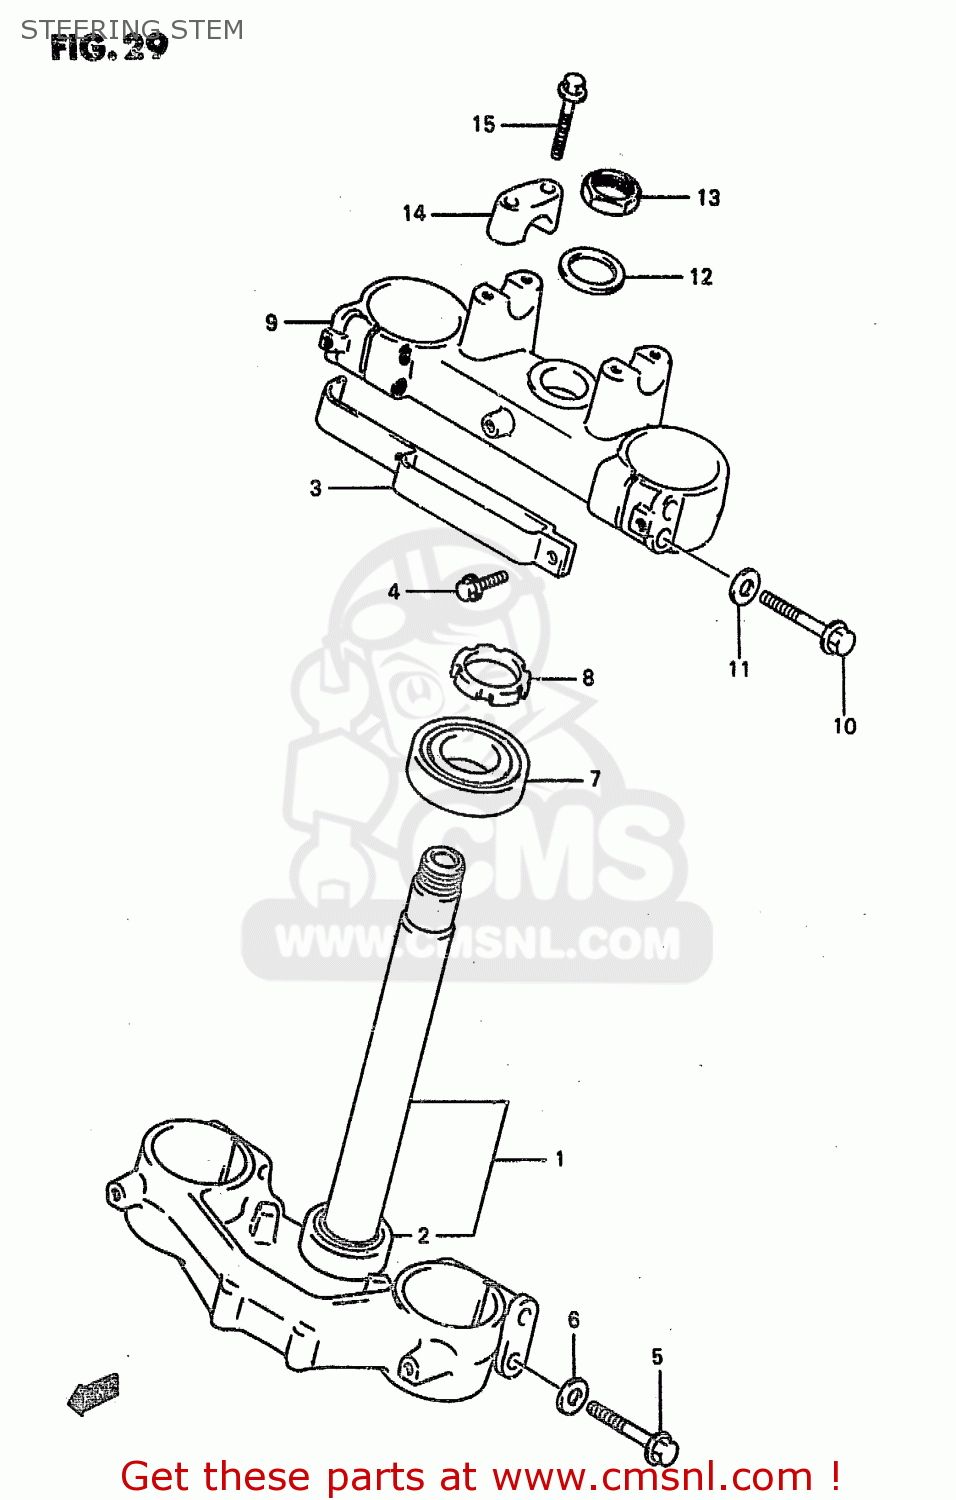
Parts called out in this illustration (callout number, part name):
1	STEM,STEERING
2	BEARING(30X52X16)
3	GUIDE,FR BRAKE HOSE
4	BOLT,PROTECTOR(6X10)
5	BOLT
6	WASHER
7	BEARING(30X52X16)
8	NUT,STEERING
9	HEAD,STEERING STEM
10	BOLT
11	WASHER
12	WASHER,STEM HEAD
13	NUT,STEM HEAD
14	HOLDER,HANDLEBAR
15	BOLT,HANDLE HOLDER(8X35)
